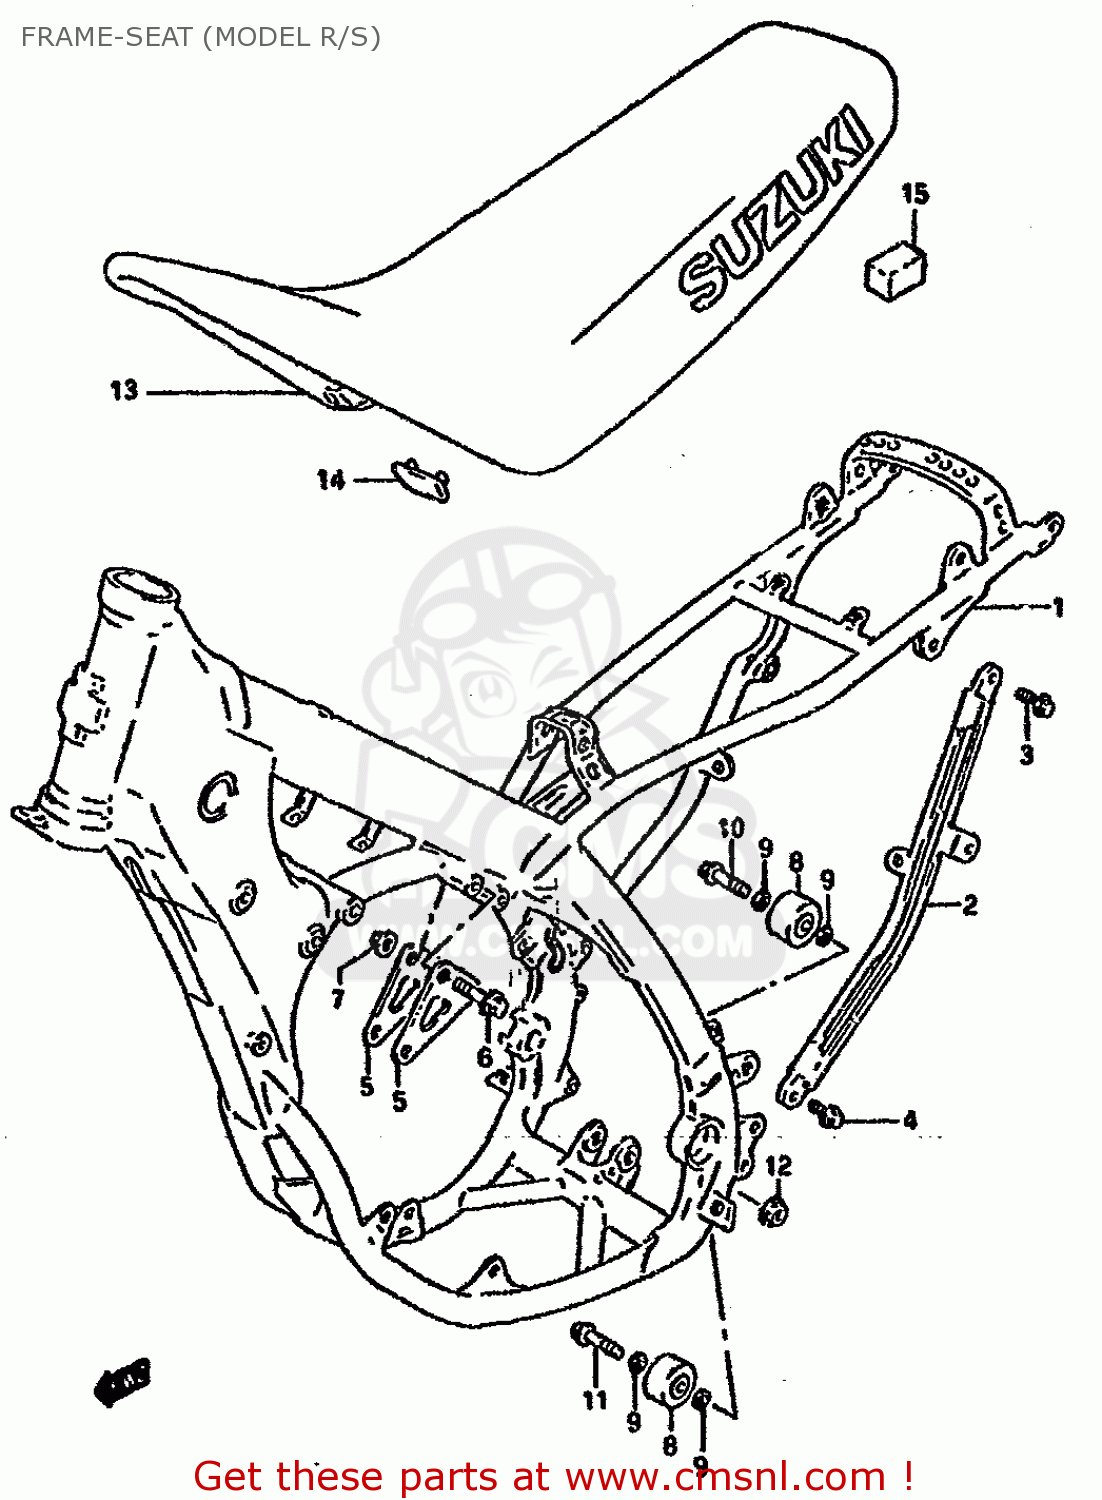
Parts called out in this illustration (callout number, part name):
1	FRAME
2	TUBE,FRAME SIDE,L
3	BOLT
4	BOLT, LOWER
5	PLATE,ENGINE MOUNT UPR
6	BOLT(8X41)
7	NUT
8	ROLLER,CHAIN
9	WASHER
10	BOLT(8X41)
11	BOLT(8X45)
12	NUT
13	SEAT ASSEMBLY
14	CUSHION
15	CUSHION,SEAT
